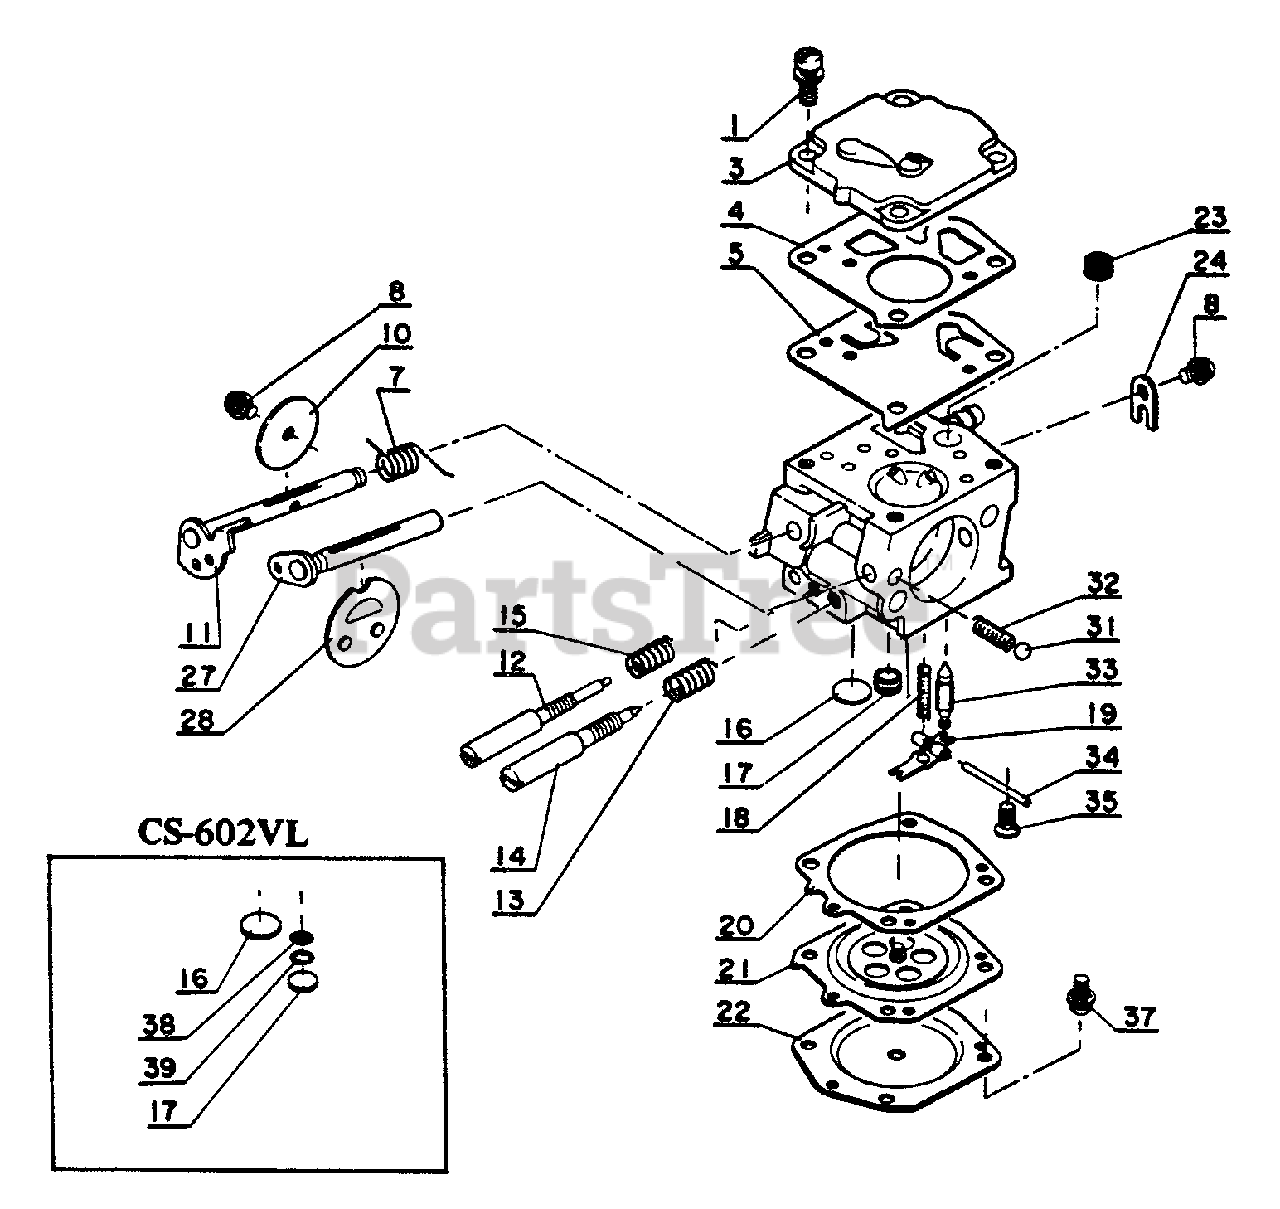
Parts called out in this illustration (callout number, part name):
1	SCREW
3	COVER, PUMP
4	GASKET, PUMP
5	DIAPHRAGM, PUMP
7	SPRING, RETURN
8	SCREW
10	VALVE, THROTTLE
11	SHAFT, THROTTLE
12	SCREW, IDLE ADJUST
13	SCREW, IDLE ADJUST
14	SCREW, MAIN ADJUST
15	SPRING, IDLE ADJUST
15	SCREW, IDLE ADJUST
16	PLUG, WELCH - LARGE
17	VALVE, CHECK
17	PLUG, WELCH - SMALL
18	SPRING, TENSION
19	LEVER, METERING
20	GASKET, METERING DIAPHRAGM
21	DIAPHRAGM
22	COVER, DIAPHRAGM
23	FILTER, FUEL
24	CLIP, THROTTLE SHAFT
27	SHAFT, CHOKE
28	VALVE, CHOKE
31	BALL, CHOKE SET
32	SPRING, CHOKE SET
33	VALVE, INLET NEEDLE
34	PIN, METERING LEVER
35	SCREW, METERING LEVER PIN
37	SCREW
38	SCREEN - CS-602VL
39	RING, RETAINING
